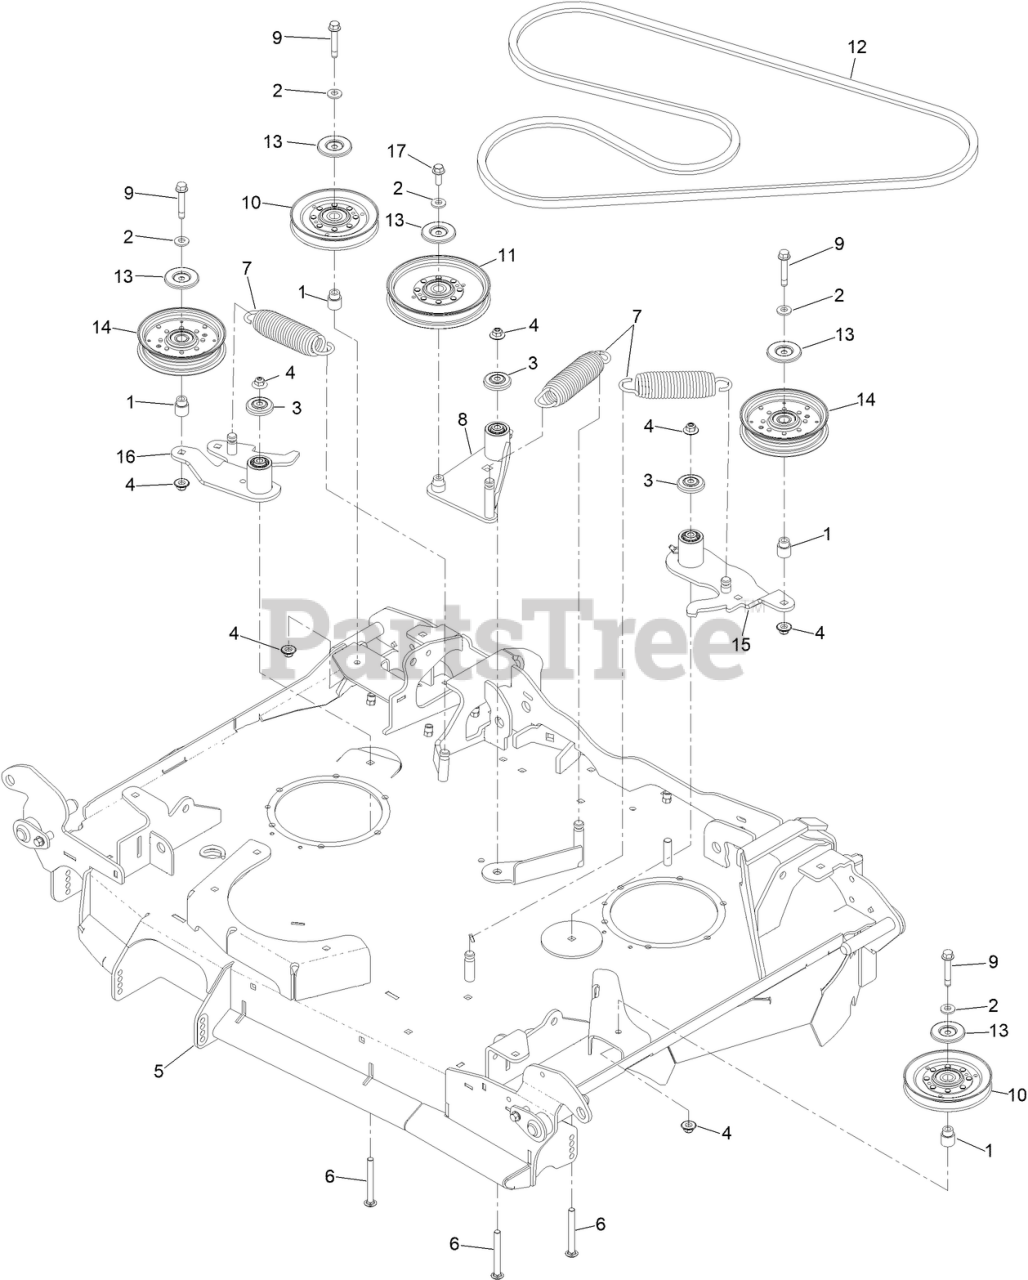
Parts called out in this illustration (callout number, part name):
1	BUSHING-IDLER
2	WASHER-BELLEVILLE
3	GUARD-TOP
4	NUT-FLANGE, NI
5	ASM-DECK, CTR [W/DECALS]
6	BOLT-SHOULDER, CARRIAGE
7	SPRING-EXTENSION
8	IDLER ARM ASM
9	SCREW-HHF W/ PATCH
10	IDLER-V
11	IDLER-PULLEY
12	V-BELT
13	SHIELD-DUST
14	PULLEY-IDLER, FLAT
15	IDLER ASM
16	IDLER ASM
17	SCREW-HHF
